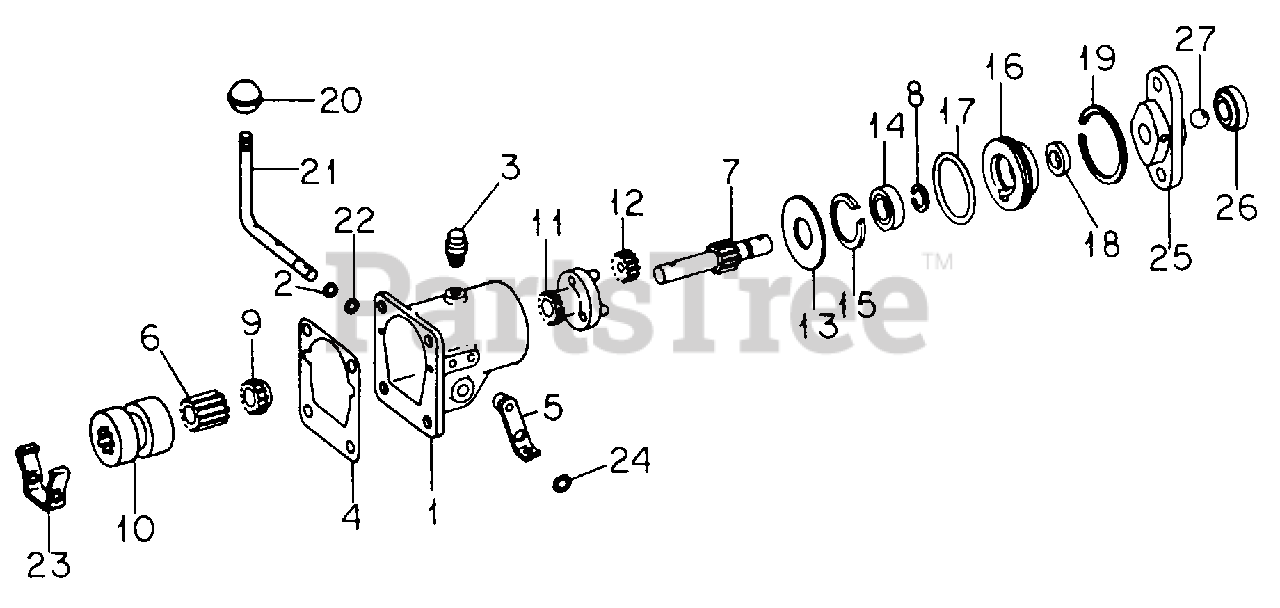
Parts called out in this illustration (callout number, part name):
1	Housing Assy, Creeper Drive
2	O-Ring, 3/8 X 1/2 X 1/16
3	Breather, Creeper Drive Housing
4	Gasket, Creeper Drive Housing
5	Lever Assy, Creeper Shift Poppet
6	Coupling Assy, Driven
7	Shaft, Creeper Drive Input
8	Ring, Creeper Drive Input Shaft Snap
9	Coupling, Direct Drive
10	Collar, Shifter
11	Carrier Assy, Planet
12	Gear, Planet
13	Washer, Planet Gear Thrust
14	Bearing, Creeper Input Shaft Ball
15	Ring, Input Shaft Snap
16	Cage, Input Shaft Brg
17	O-Ring, 2-7/16 X 2-5/8 X 3/32
18	Seal, Input Shaft Brg Cage Oil
19	Ring, Input Shaft Brg Cage Retainer Snap
20	Knob, Creeper Shift Lever
21	Lever, Creeper Shift
22	O-Ring, 1/4 X 3/8 X 1/16
23	Yoke, Creeper Shift
24	Spacer, Poppet Lever
25	Coupler, Driveshaft
26	Bushing, Ball
27	Ball, 5/8 Cr Stl
